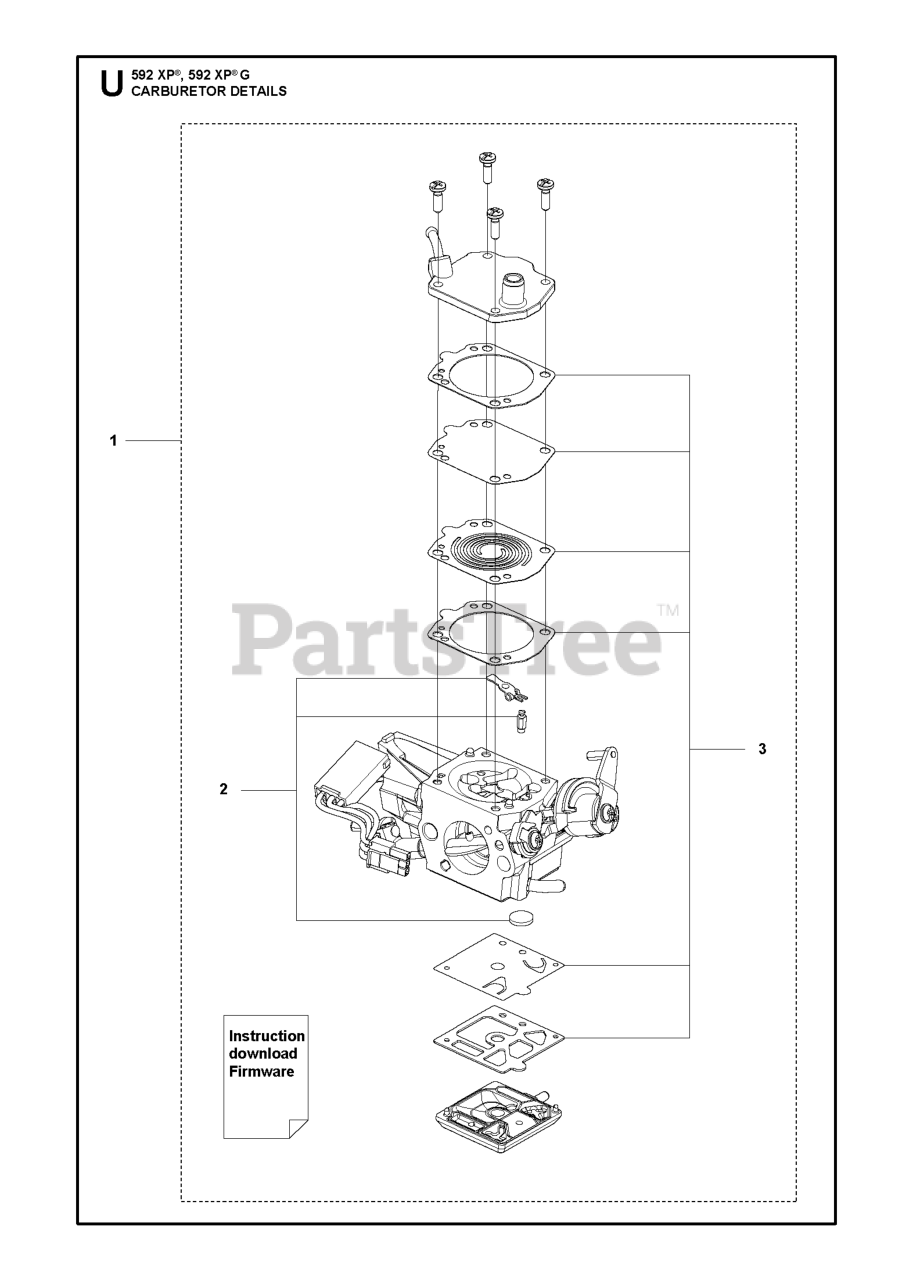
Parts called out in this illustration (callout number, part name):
1	CARBURETTOR KIT H592
2	REPAIR KIT 592/585 CARB
3	GASKET KIT 592 CARB
